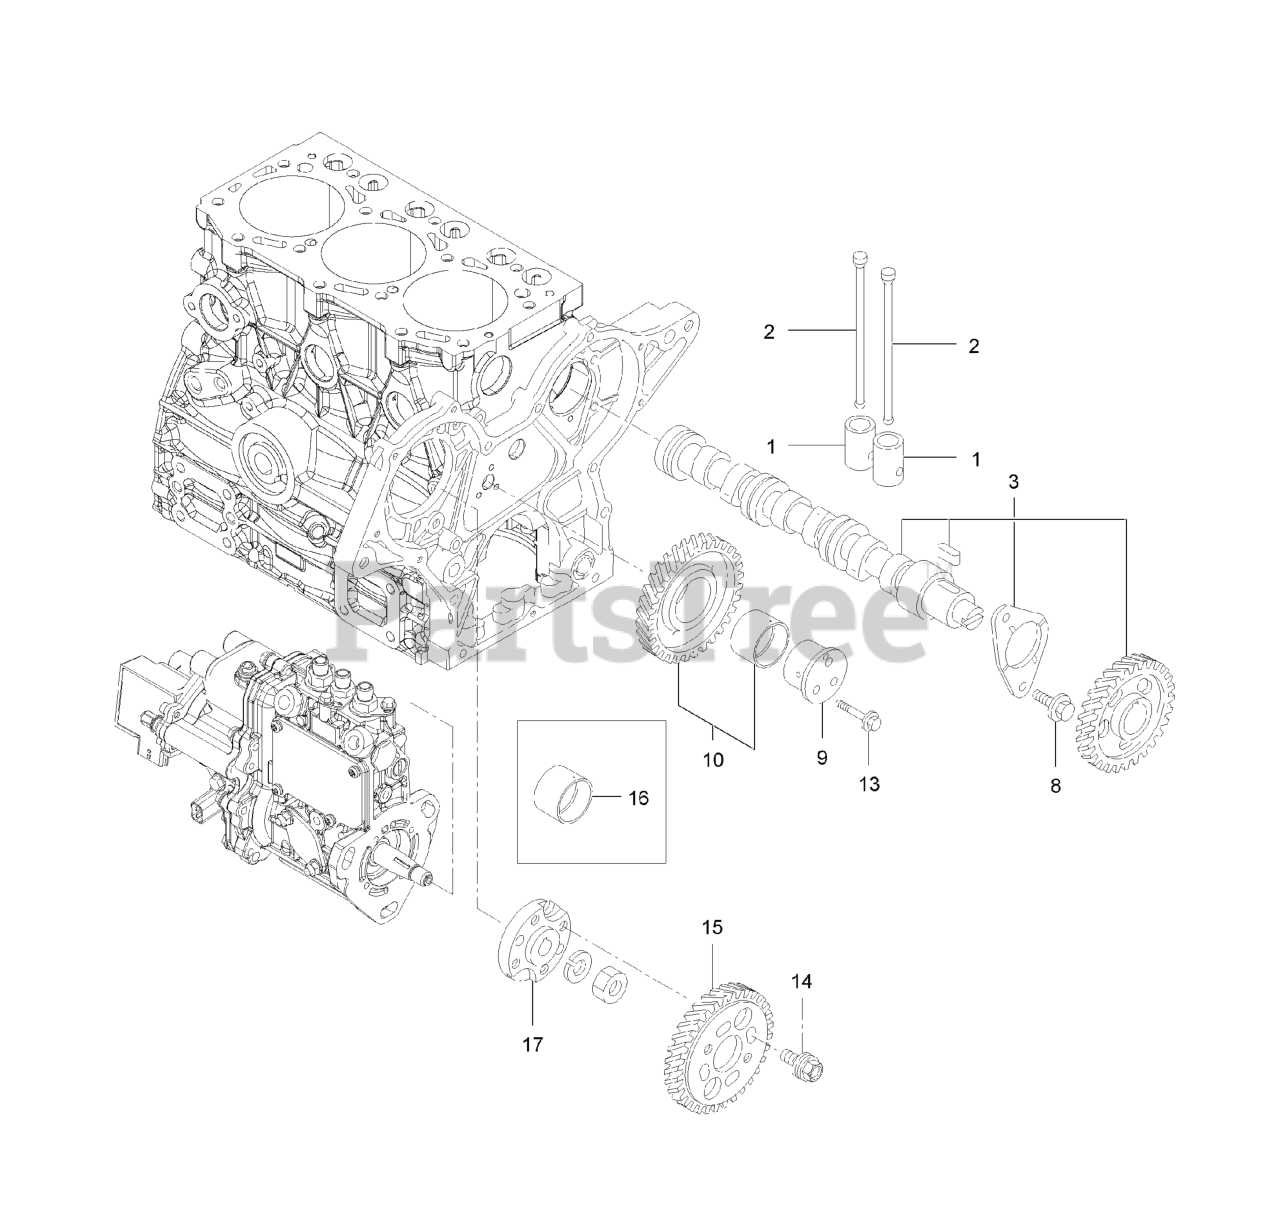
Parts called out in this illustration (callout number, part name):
2	PUSH-ROD
3	CAMSHAFT ASM
9	SHAFT-IDLE
10	GEAR ASSY-IDLE
15	GEAR-PUMP
16	BUSH-IDLE GEAR
